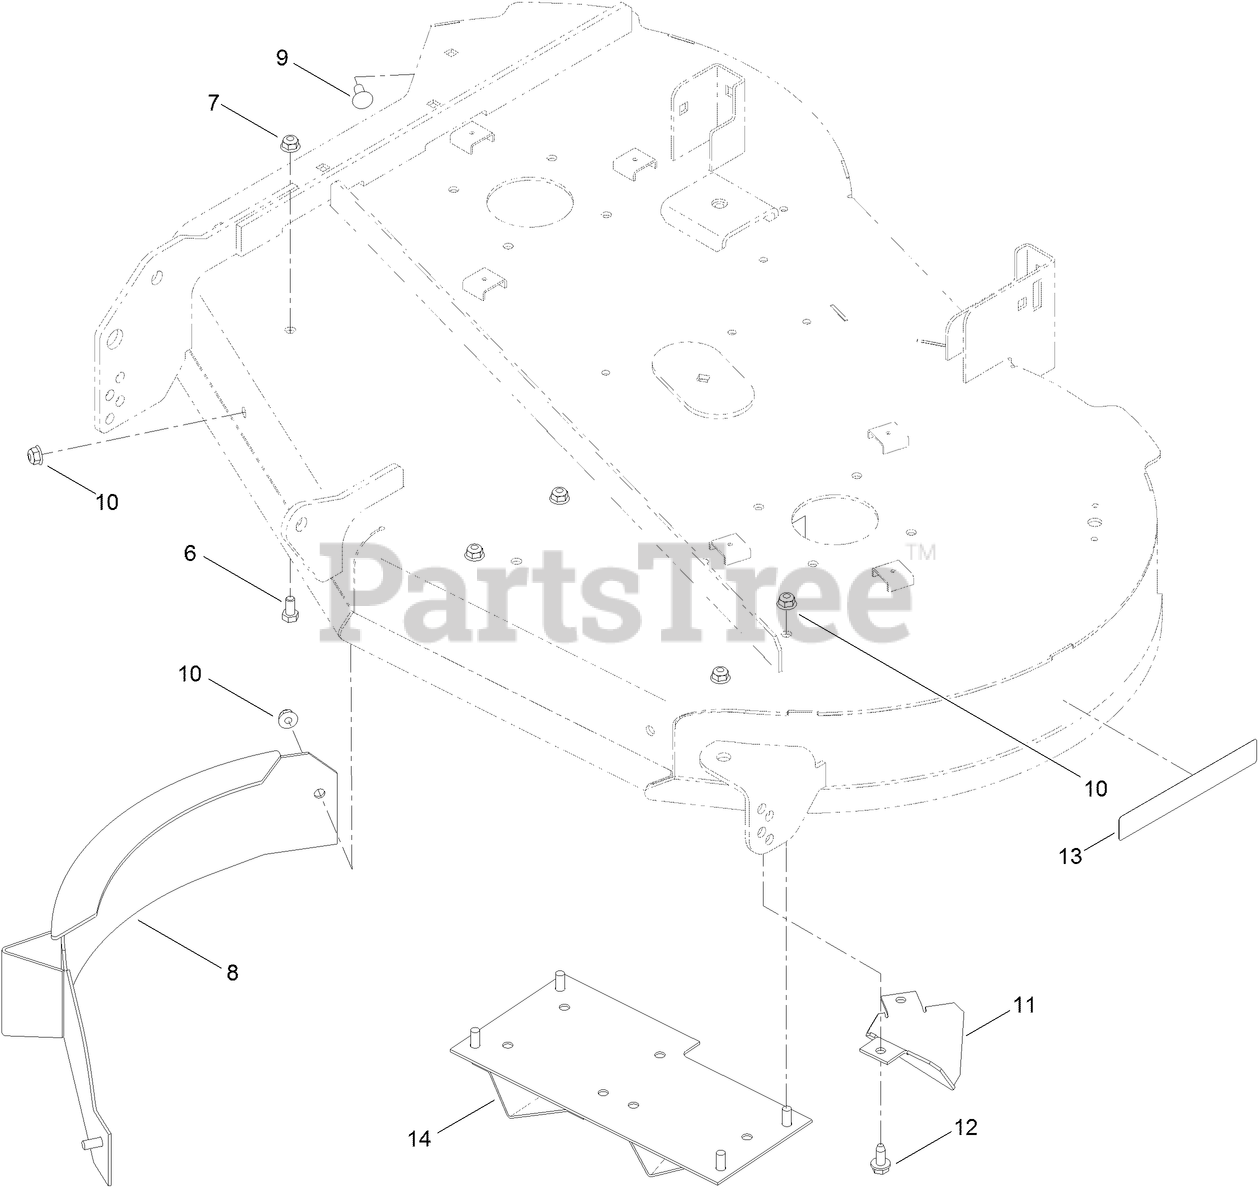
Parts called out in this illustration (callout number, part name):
6	SCREW-HH
7	NUT-HF, NI
8	BAFFLE ASM
9	BOLT-CARR
10	NUT-HF, NI
11	KICKER-FLANGED
12	SCREW-HWHTF
13	DECAL-RECYCLER
14	KICKER ASM
